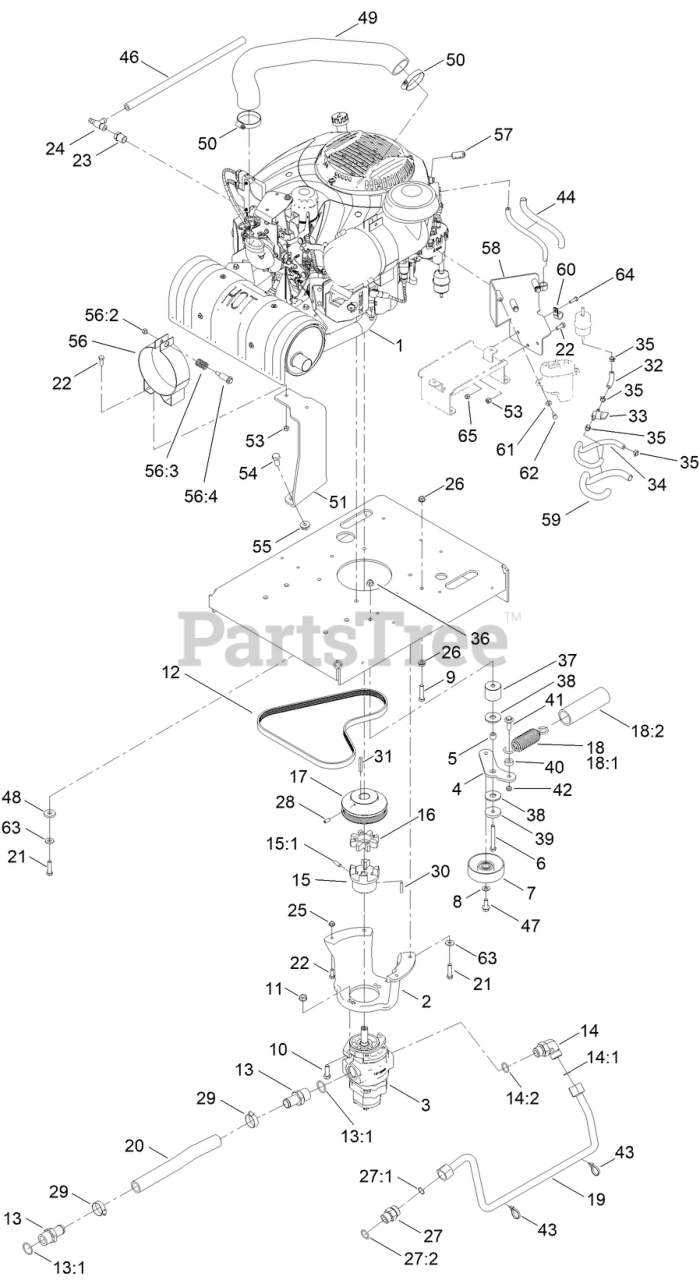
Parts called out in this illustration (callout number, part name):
1	ENGINE-KOHLER
2	MOUNT-PUMP [PRIMED]
3	GEAR PUMP ASM
4	ARM-IDLER
5	BUSHING-LEVER, LIFT
6	SCREW-HH
7	PULLEY-IDLER
8	WASHER-FLAT
9	SCREW-HH
10	SCREW-HH
11	NUT-HF
12	BELT-V
13	FITTING-STR
13:1	O-RING
14	FITTING-ELBOW-90
14:1	O-RING
14:2	O-RING
15:1	SCREW-SET
16	SPIDER
18	SPRING AND RETAINER KIT
18:1	SPRING-EXTENSION
18:2	RETAINER-SPRING
19	TUBE-HYD
20	HOSE-SUCTION
21	SCREW-HH
22	SCREW-HH
23	BUSHING
24	VALVE-DRAIN, OIL
25	NUT-HF
26	NUT-HHF, WHIZ
27	FITTING-HYD, STRAIGHT
27:1	O-RING
27:2	O-RING
28	SCREW-SET, HSH
29	CLAMP-HOSE
30	KEY-SQUARE
31	KEY-SQUARE
32	HOSE-FUEL
33	VALVE-FUEL
34	HOSE-FUEL
35	CLAMP-HOSE
36	NUT-HF, NI
37	SPACER-IDLER
38	WASHER-FRICTION, COMPOSITE
39	WASHER-PLAIN
40	SPACER
41	SCREW-SHOULDER, HWH
43	TIE-CABLE
44	SLEEVE-THERMAL
47	SCREW-HHF
48	WASHER
49	HOSE-INTAKE, AIR
50	CLAMP-HOSE
51	PLATE-MOUNT, FILTER
53	NUT-LOCK, NI
54	SCREW-HH
55	NUT-HHF
56	BAND-MOUNTING, AIR CLEANER
56:3	SPRING
56:4	NUT-LOCK, NI
57	FERRITE-SNAP ON
58	BRACKET-PUMP, FUEL
59	SLEEVE-THERMAL
60	CLAMP-CABLE
61	WASHER-FLAT
62	SCREW-HH
63	WASHER-BELLEVILLE
64	SCREW-HH
65	NUT-LOCK, NI
